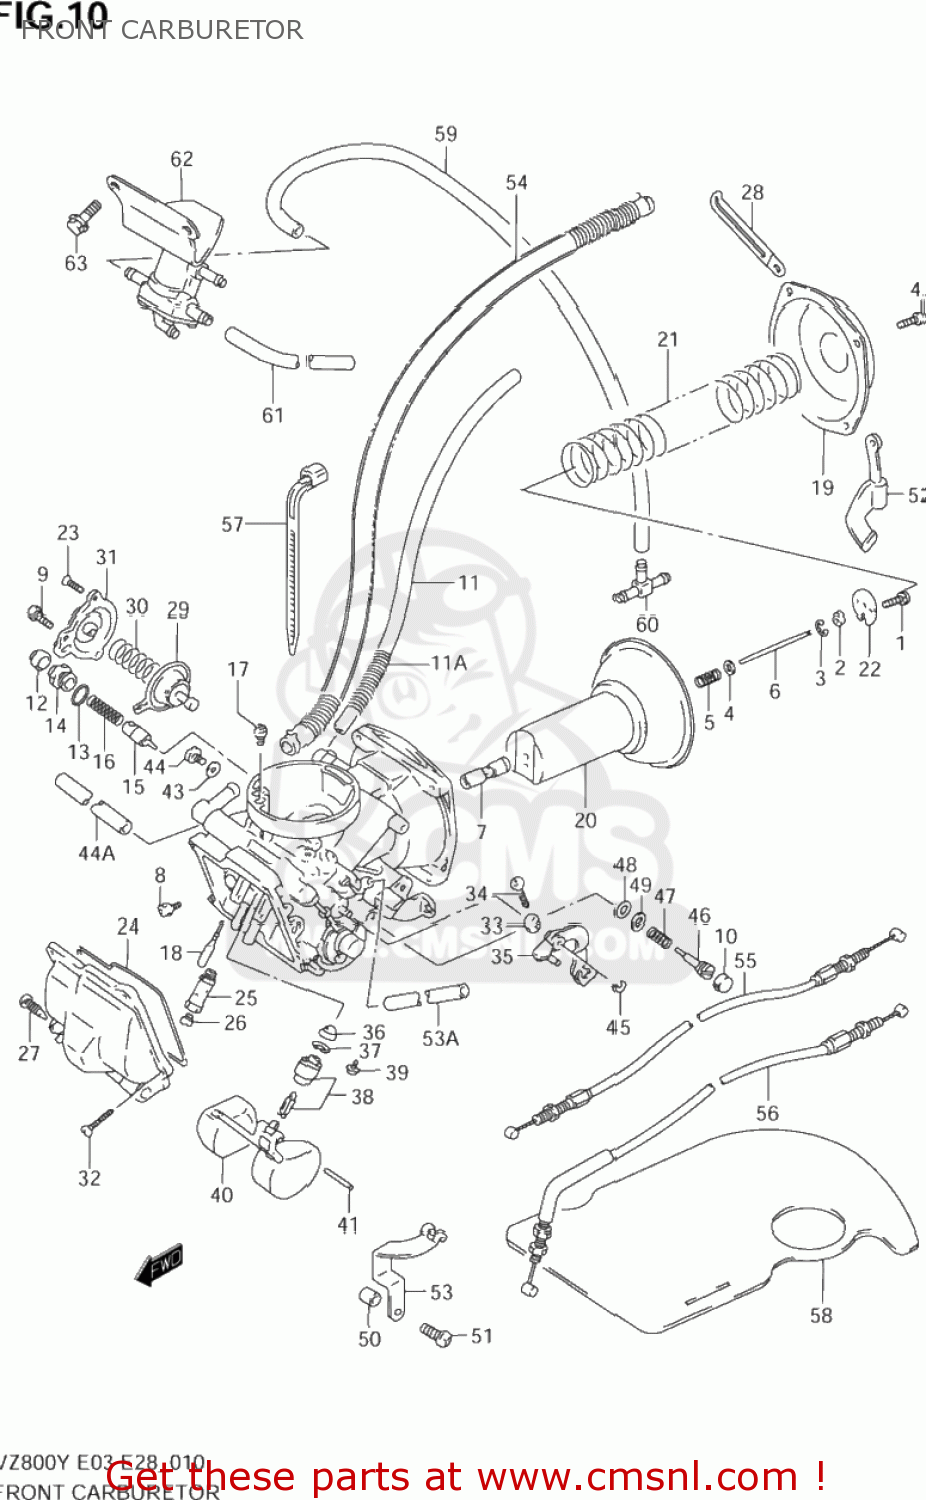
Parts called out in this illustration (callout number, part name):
1	SCREW
2	RING
3	CLIP
4	WASHER
5	SPRING
6	NEEDLE,JET(5C43-1)
7	JET,NEEDLE(P-4M)
8	SCREW
9	SCREW
10	PLUG
11	HOSE
11A	SPRING
12	CAP
13	O RING
14	HOLDER,GUIDE
15	PLUNGER,STARTER
16	SPRING
17	JET,AIR(65)
18	JET,PILOT(40)
19	COVER
20	DIAPHRAGM,CARBURETOR
21	SPRING,DIAPHRAGM
22	PLATE
23	SCREW,UPPER
24	O RING,FLOAT CHAMBER
25	HOLDER,MAIN JET
26	JET,MAIN(90)
27	PLUG,DRAIN
28	CLAMP(L:65)
29	DIAPHRAGM ASSY
30	SPRING
31	COVER
32	SCREW
33	NUT
34	SCREW
35	LEVER ASSY
36	FILTER
37	O-RING,NEEDLE VALVE
38	VALVE ASSY,NEEDLE
39	SCREW
40	FLOAT
41	PIN,FLOAT
42	SCREW
43	GASKET,DRAIN PLUG (NAS)
44	SCREW(5X6)
44A	HOSE
45	E RING
46	SCREW,PILOT
47	SPRING
48	O RING,PILOT AIR SCREW
49	WASHER
50	RING
51	SCREW
52	BRACKET
53	BRACKET
53A	HOSE ASSY(5X8X125)
54	HOSE ASSY
55	CABLE,IDLE SYNCRO
56	CABLE,THROTTLE RETURN F-R
57	CLAMP L:165
58	SHEET HEAT SHIELD
59	HOSE
60	NIPPLE
61	HOSE(5X10X600)
62	VALVE,AIR VENT
63	BOLT
